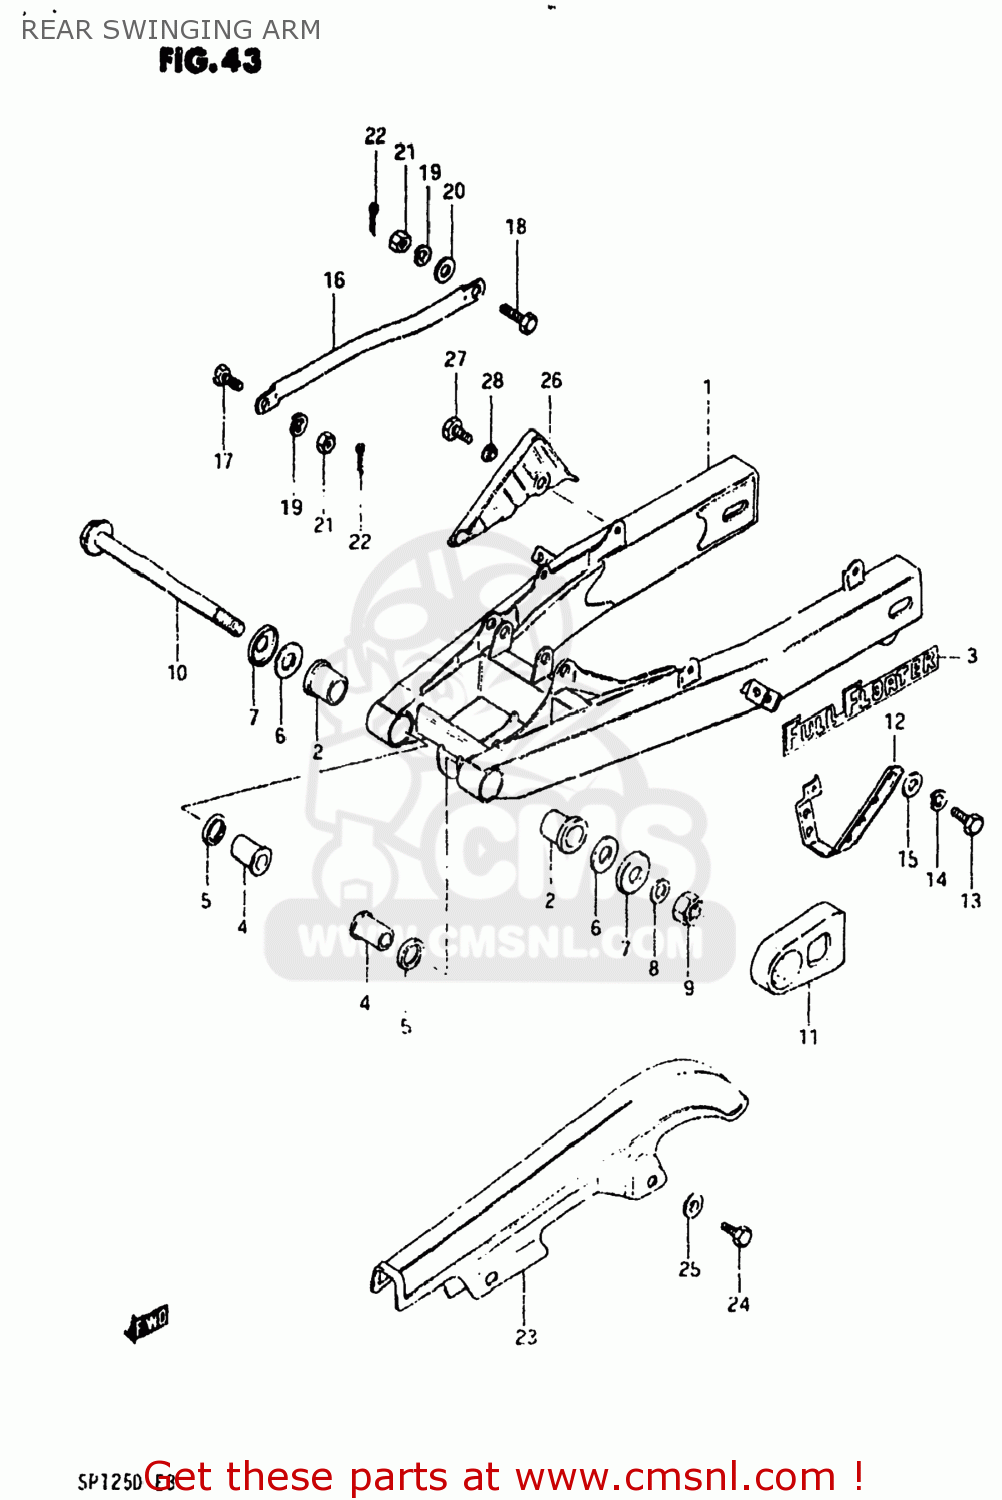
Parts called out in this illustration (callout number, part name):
1	SWING ARM ASSEMBLY,REAR
2	BUSHING,REAR SWING ARM PIVOT
3	EMBLEM
4	SPACER,RR SWGARM PIVOT
5	SEAL,OIL(20X27X5)
6	WASHER
7	CVR,RR SWGARM DUST SEAL(OD:40)
8	WASHER
9	NUT 14MM
10	SHAFT,REAR SWING ARM
11	BUFFER,CHAIN TOUCH DEFENSE
12	GUIDE,CHAIN
13	BOLT 8X12
14	LOCK WASHER
15	WASHER
16	TORQUE LINK,REAR
17	BOLT(8X22)
18	BOLT(8X26.5)
19	LOCK WASHER
20	WASHER
21	NUT
22	PIN 20X20
23	CASE,CHAIN
24	BOLT 6X8
25	WASHER
26	GUARD,PILLION FOOT
27	BOLT 6X8
28	WASHER
